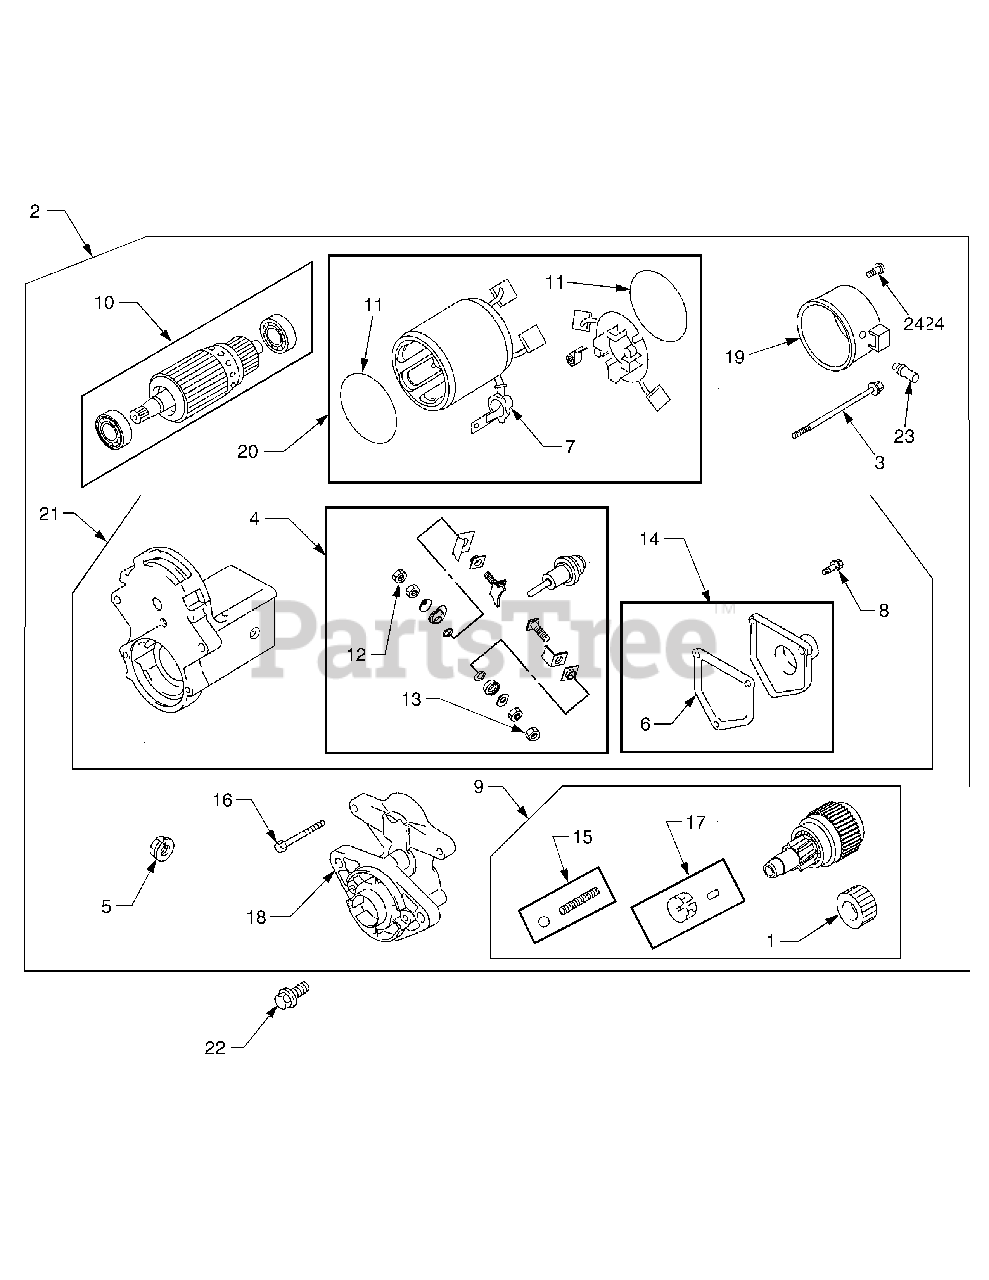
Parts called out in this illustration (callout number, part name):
1	Gear, Starter Drive
2	Motor, Starter
3	Screw, Starter Motor
4	Plunger-Solenoid
5	Nut, Starter Motor Terminal
6	Gasket, Solenoid Cover
7	Boot, Terminal
8	Screw, Solenoid Cover
9	Drive, Starter
11	Seal, O-Ring
12	Nut, Solenoid Terminal
13	Nut, Solenoid Terminal
14	Cover, Solenoid
15	Spring, Detent
16	Screw, Drive Cap
17	Clutch Roller
18	Cap, Drive
20	Housing, Starter (Includes 2 Brushes)
21	Solenoid, Starter
22	Screw, Starter Motor
23	Plug, Vent
24	Screw, End Cap
